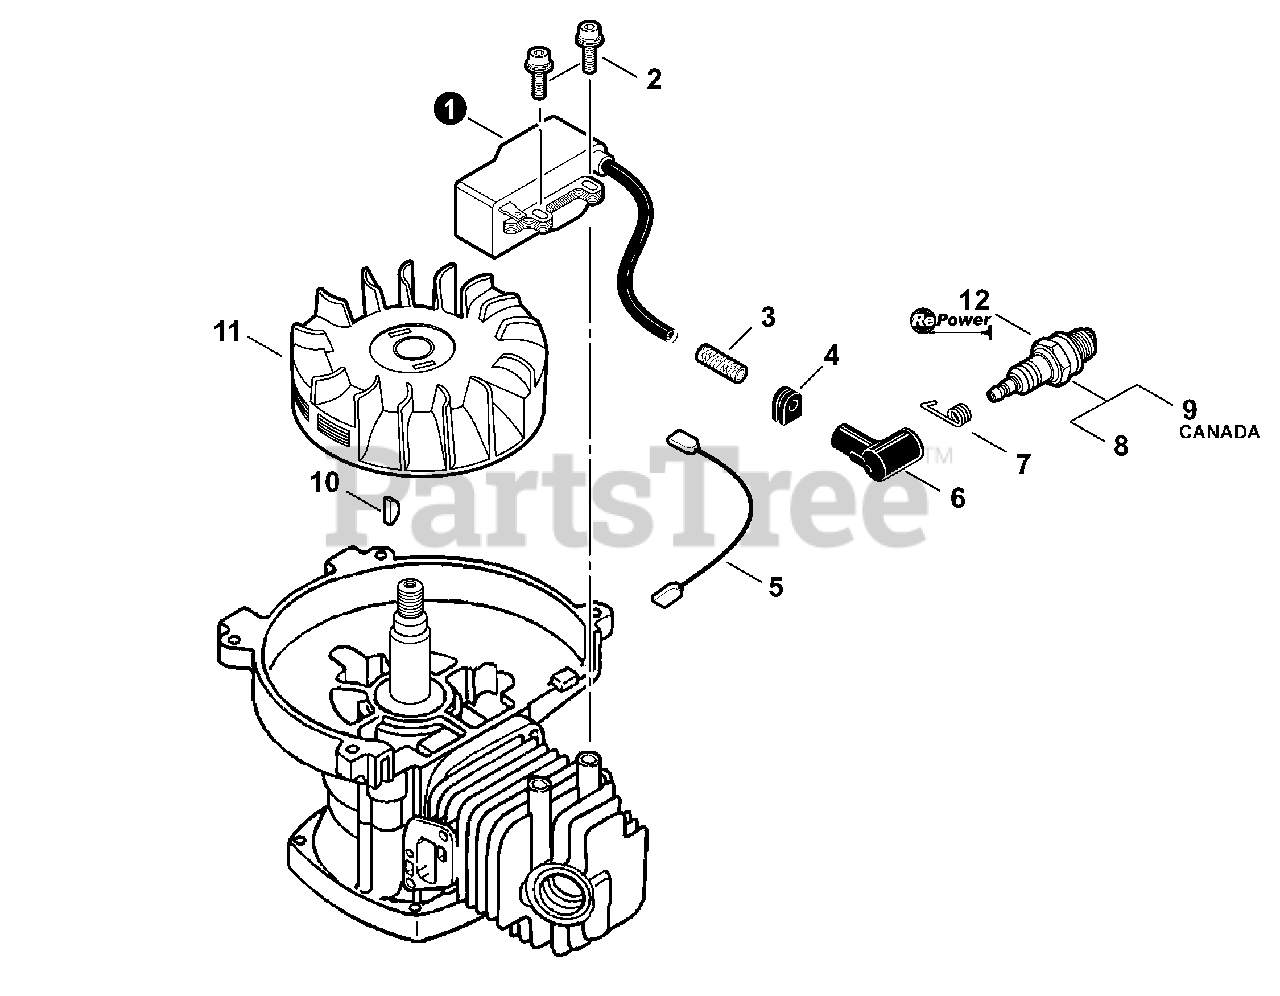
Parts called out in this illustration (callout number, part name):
1	COIL, IGNITION
2	BOLT 4×20
3	TUBE, INSULATOR
5	LEAD - GROUND
6	CAP, SPARK PLUG
7	TERMINAL, SPARK PLUG
8	SPARK PLUG - BPM8Y
9	SPARK PLUG - BPMR8Y
11	FLYWHEEL
12	TUNE-UP KIT - REPOWER
